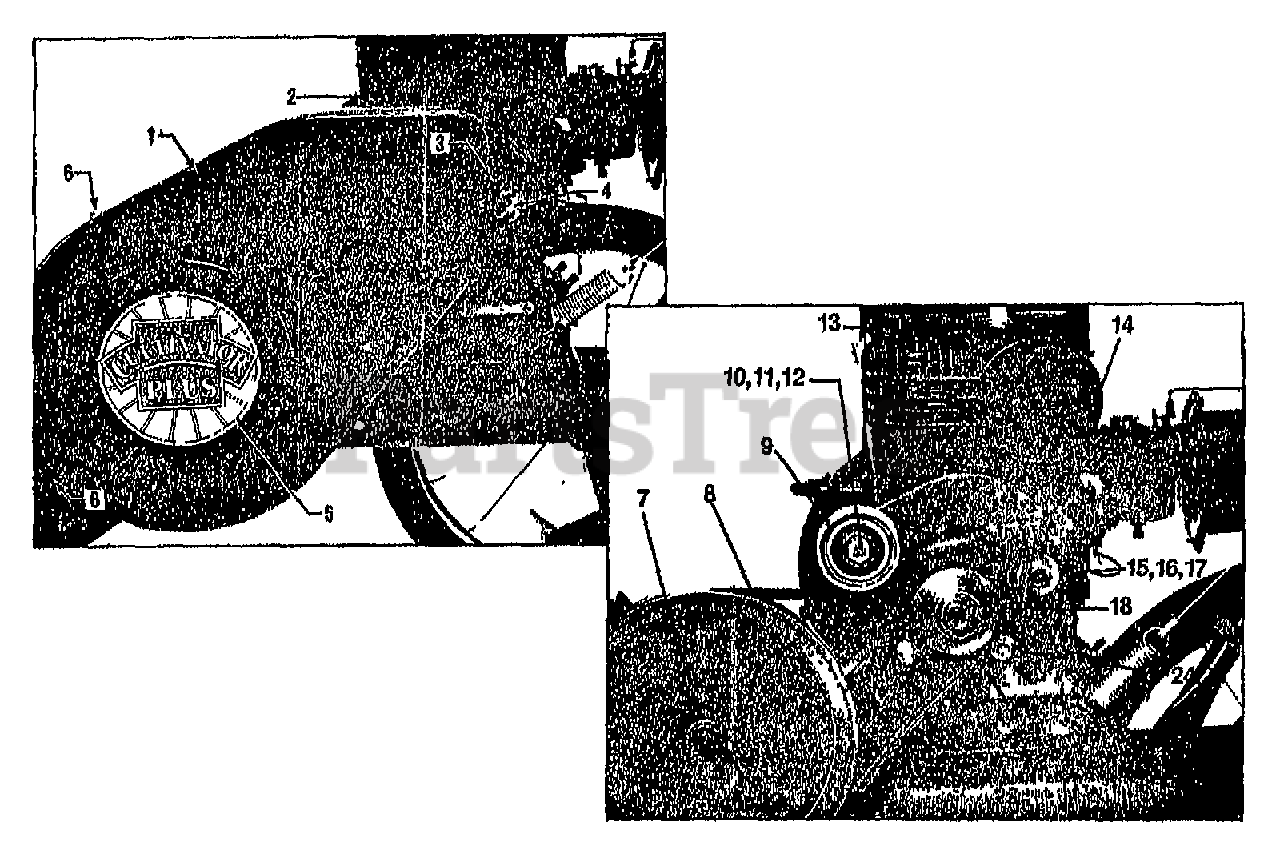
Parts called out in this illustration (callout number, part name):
1	COVER-BELT W/DECAL (INCL. 60028,9368, 60071, 60074)
2	DECAL-BELT GUARD WARN 60074
3	CUSHION
4	PIN-HITCH ZP
5	DECAL-"CULTIVATOR-PLUS"
6	SCR-HW M10-24X.375 ZP (ATTACHES BELT COVER TO PIVOT BRACKET)
7	PULLEY-DRIVEN PNT
8	BELT-V CULTIVATOR
9	PULLEY-IDLER ZP
10	BOLT-HH 3/8-16X1.5 FTH ZP (ATTACHES IDLER PULLEY TO SHAFT)
11	BUSHING-.5X.38X.4 (LOCATED BEHIND IDLER PULLEY)
12	NUT-H/LK 3/8-16 (LOCATED BEHIND IDLER PULLEY)
13	ASSM-IDLER ARM
14	BRKT-LOCKING PNT
15	SCR-HH 5/16-18X.5 GD5 YEL (ATTACHES IDLER ARM LOCKING BRACKET TO ENGINE)
16	WASHER-LK .312 ZP
17	WASHER-#1.125X.344 ZP
18	ASSM-IDLER PLATE
24	SCR-HH 5/16-24X.75 G5 ZP
